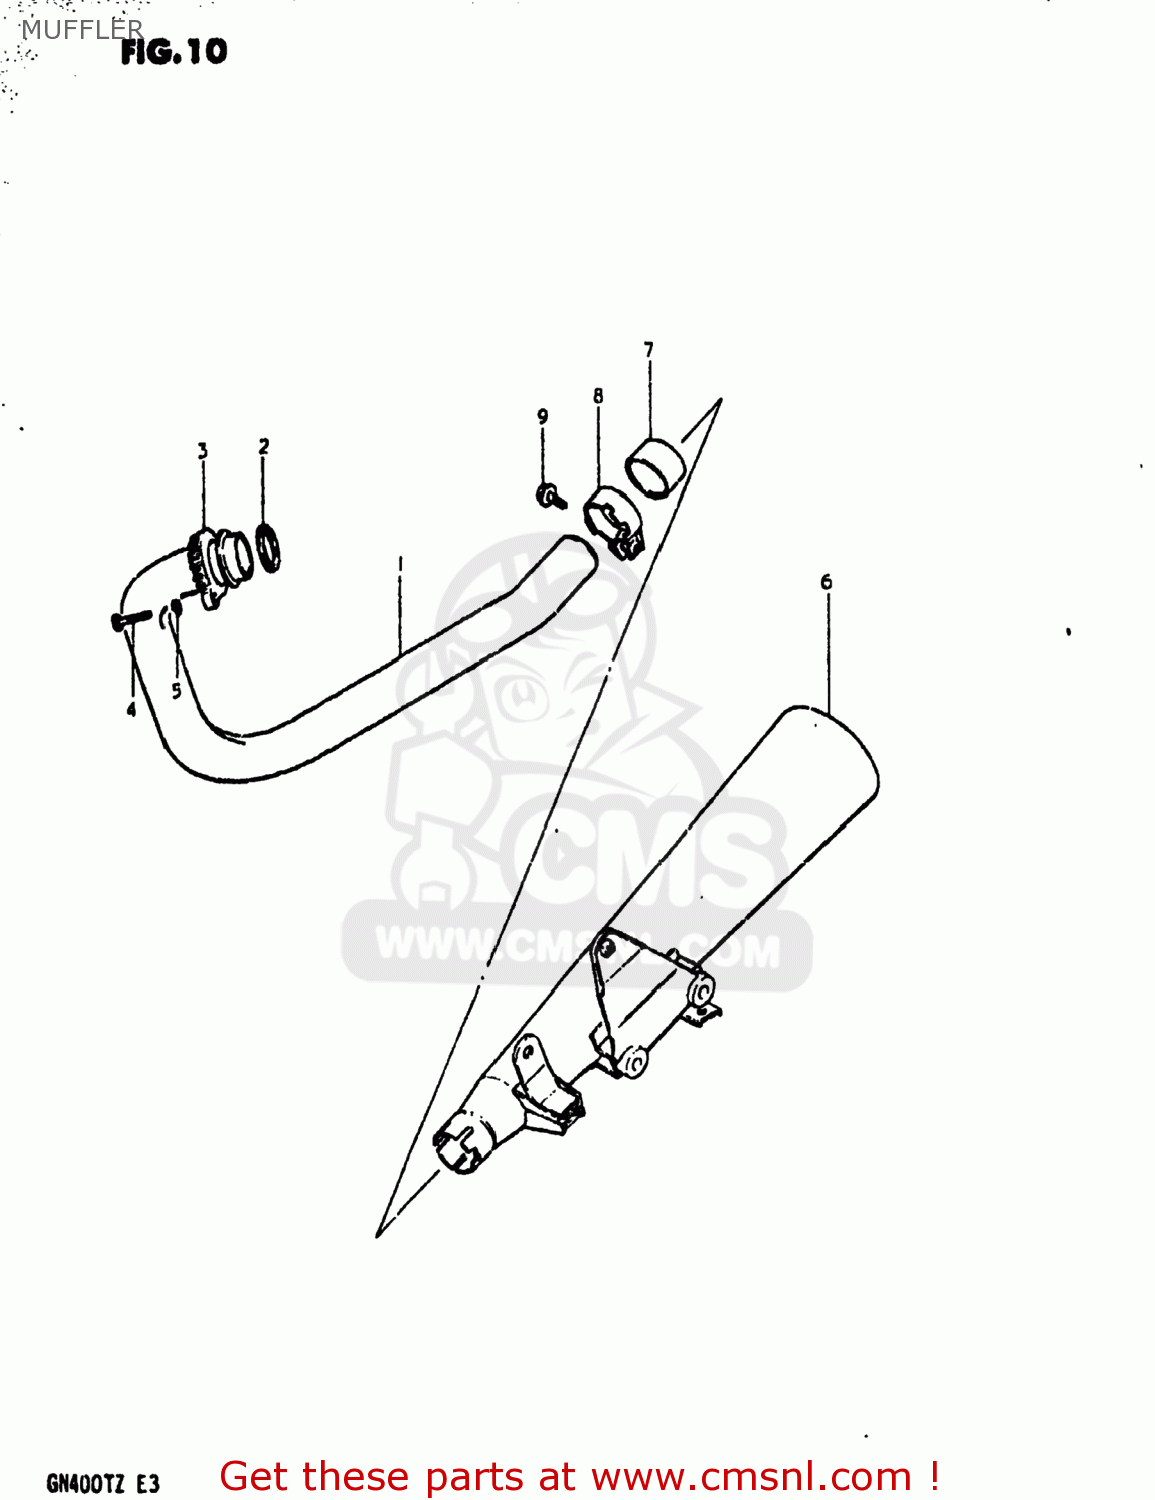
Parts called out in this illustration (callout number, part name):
1	PIPE,EXHAUST
2	GASKET,EXHAUST PIPE (NAS)
3	CLAMP,EXHAUST PIPE
4	BOLT
5	LOCK WASHER
6	MUFFLER ASSEMBLY
7	CONNECTOR,MUFFLER
8	CLAMP
9	BOLT 8X35
